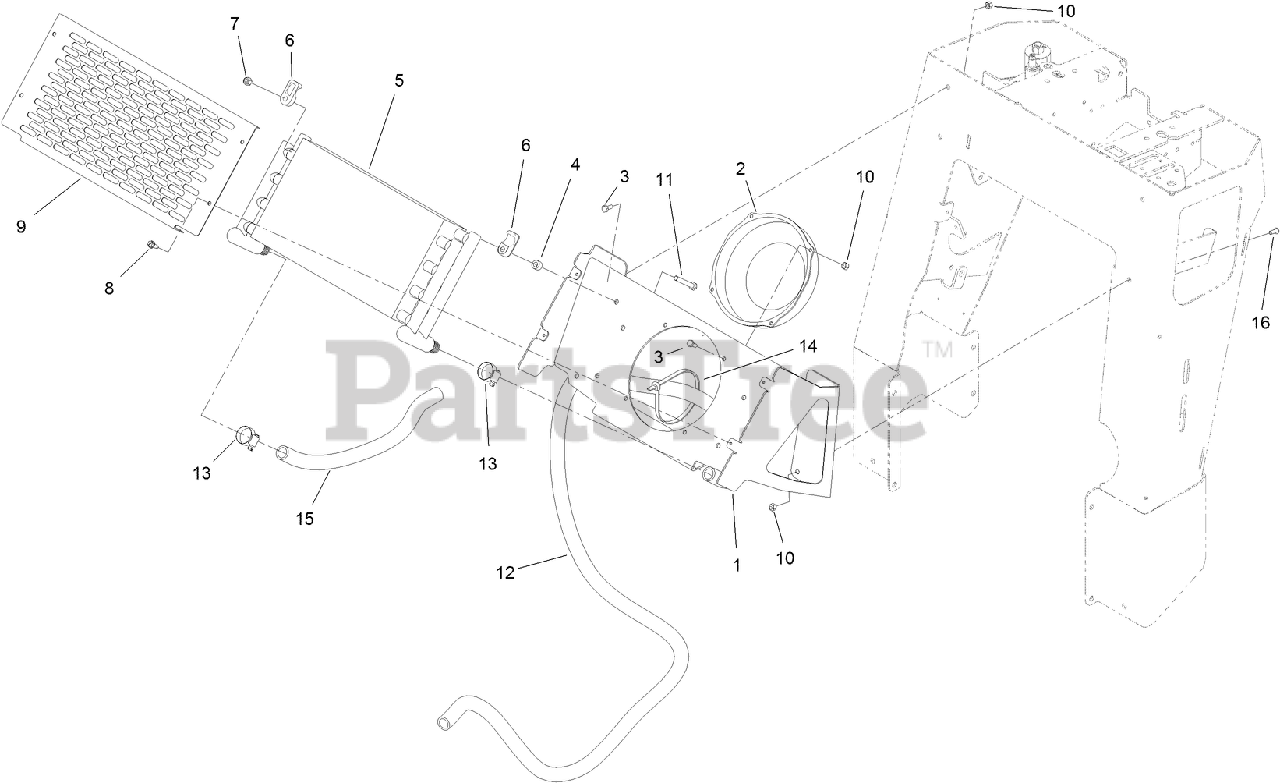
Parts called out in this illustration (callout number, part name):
1	MOUNT-COOLER
3	SCREW-HH
4	SPACER
5	COOLER-OIL
6	CLAMP-COOLER, OIL
7	NUT-LOCK, NI
8	SCREW-HWH
9	COVER-COOLER
10	NUT-LOCK, NI
11	SCREW-HH
12	HOSE-RETURN
13	CLAMP-HOSE
14	TIE-CABLE
15	HOSE-RETURN
16	SCREW-HSBH
